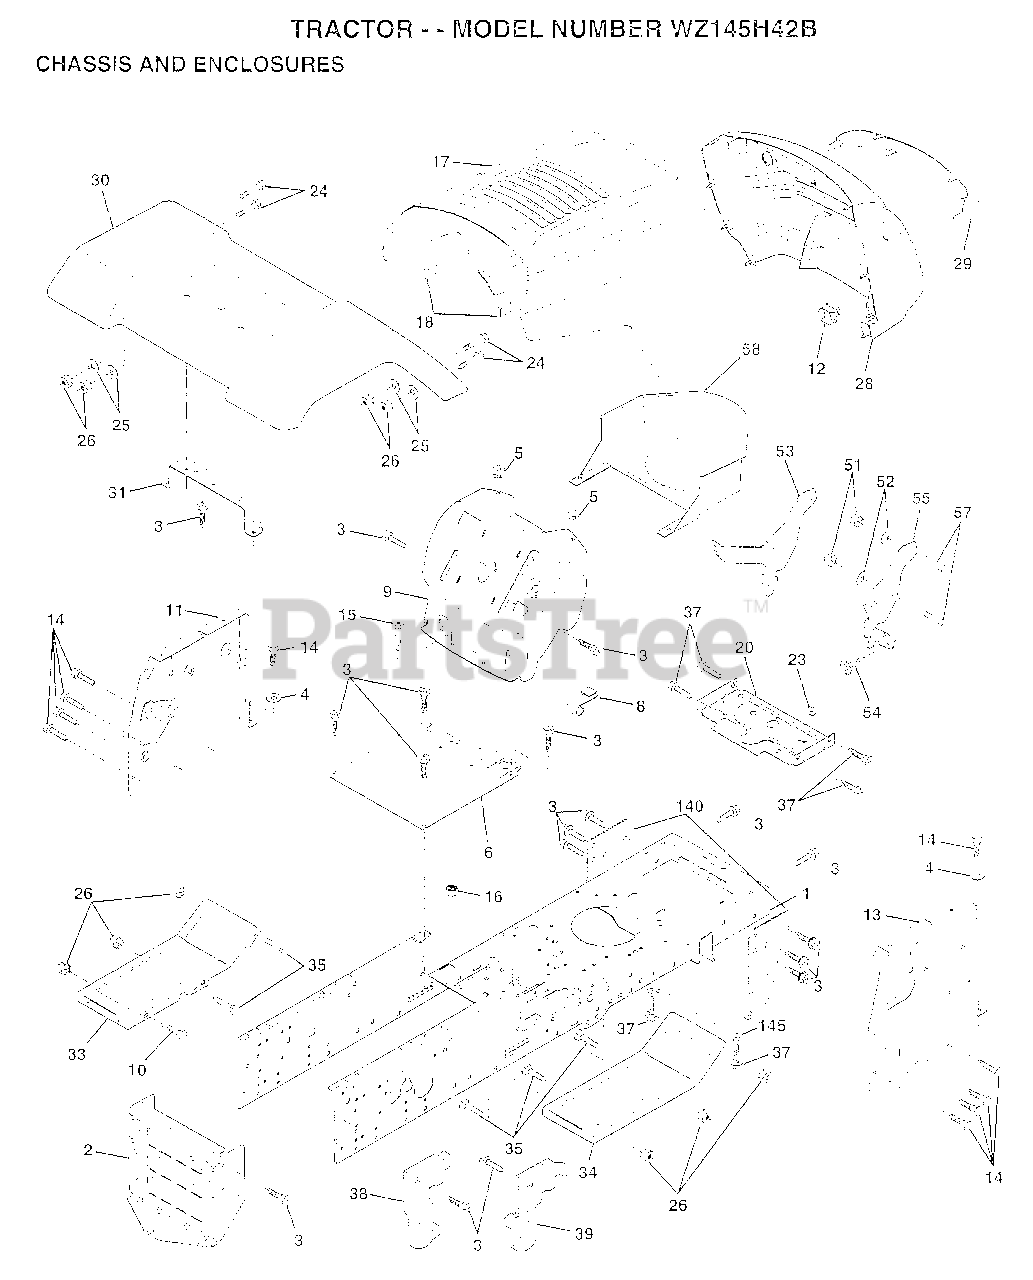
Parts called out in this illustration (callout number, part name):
3	SCREW
4	WASHER
5	BUMPER-HOOD/DASH
6	SADDLE
8	CLIP.RETAINER
9	DASH SILKSCREEN
11	"PANEL-DASH,LH"
12	CLIP.TINNERMAN
14	SCREW LT
15	SCREW
17	HOOD.STEEL.ASSY
20	"PLATE-MTG,BATT/FU"
24	BOLT
25	WASHER
26	NUT
28	GRILLE-MS428
29	LENS GRILLE
30	FENDER.LT.W/SHIFT
31	BRKT FENDER
33	FOOTREST.LH.LT/GT
34	FOOTREST.RH.LT/GT
35	BOLT
38	BRACKET ASM LH
39	BRACKET ASM RH
51	NUT
52	WASHER
53	BRACKET.GRILLE.LH
54	SCREW.HEX.WS.HD
55	BRACKET.GRILLE.RH
58	AIR DUCT
140	BRKT SUSPENSION
145	"ROD POVOT,CHASSIS"
